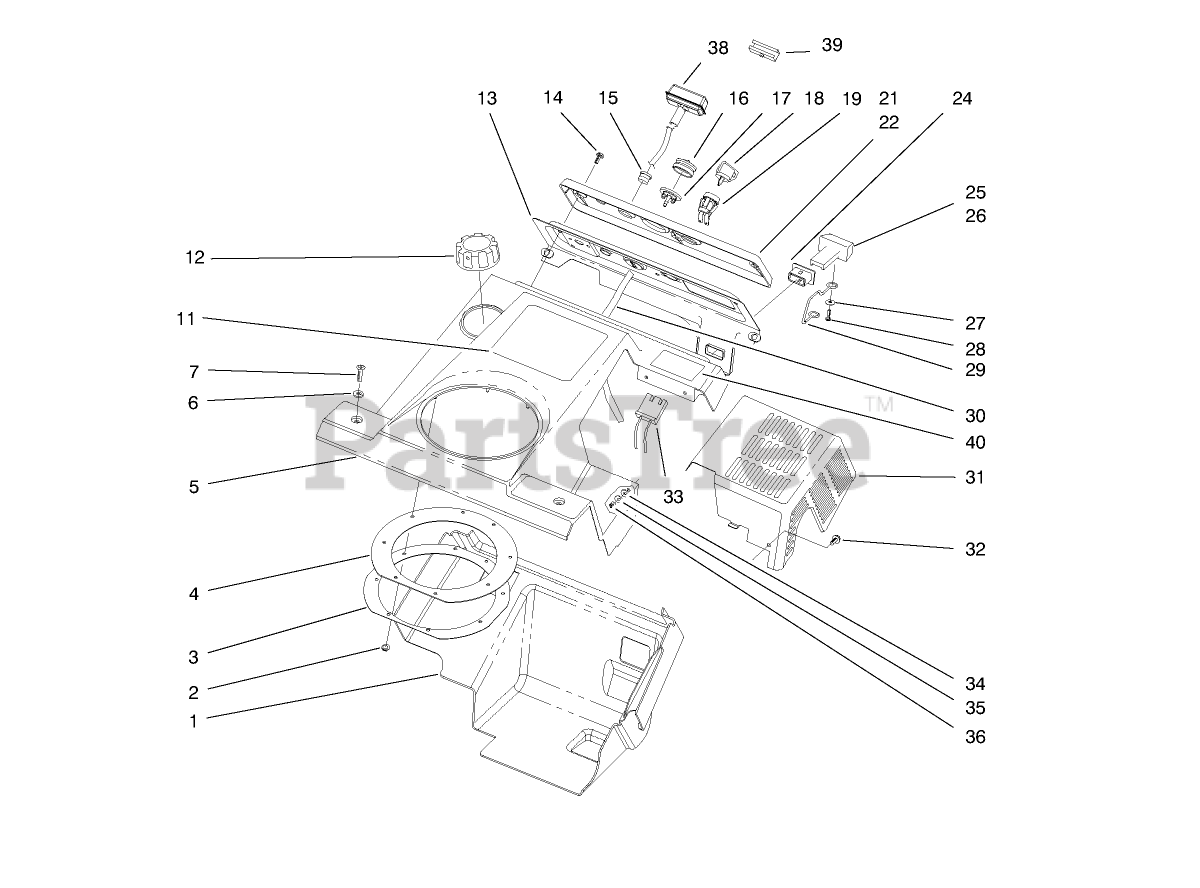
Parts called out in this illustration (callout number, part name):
2	PALNUT
6	WASHER-FLAT
7	SCREW-PPH
11	DECAL - CCR 2400 GTS
14	SCREW-HWH
15	GUIDE-ROPE, STARTER
16	BULB-PRIMER
17	BODY-PRIMER
18	KEY-IGNITION
19	SWITCH
22	NAMEPLATE-CONTROL
24	FITTING
25	CHOKE CONTROL
26	CONTROL-CHOKE
27	WASHER-PLAIN
28	SCREW-PPH
29	LINKAGE-CHOKE
30	HOSE-PRIMER
32	SCREW-SHH
33	CONNECTOR-BODY
34	WASHER
35	WASHER-FLAT
36	NUT-LOCK, NI
39	CLIP-STARTER
